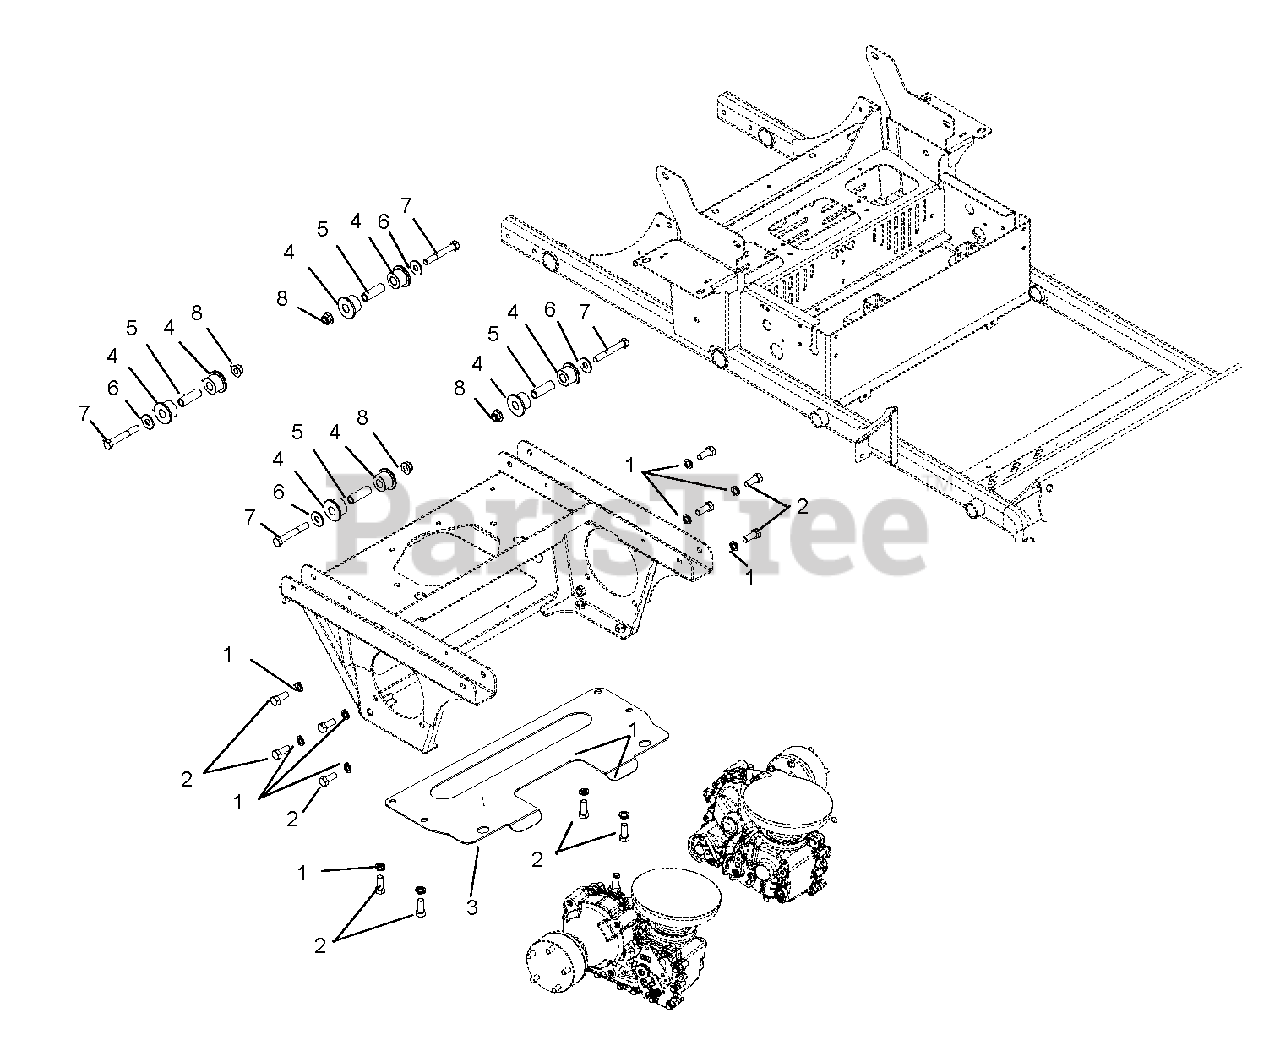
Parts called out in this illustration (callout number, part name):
1	Washer, Lock .50 x .125 REG YWZC
2	Bolt, Hex .50-13 x 1.25 GR5 YWZC
3	Plate, Transmission Skid
4	Bushing, Flange .75 x 1.51 x 1.13 x 2.0 URE
5	Bushing, Sleave .50 x .75 x 2.23
6	Washer, Flat Steel .563 x 1.38 x .109 YWZC
7	Bolt, Hex .50-13 x 3.50 GR5 YWZC
8	Nut, Locking Nylon Flange .50-13 YWZC
